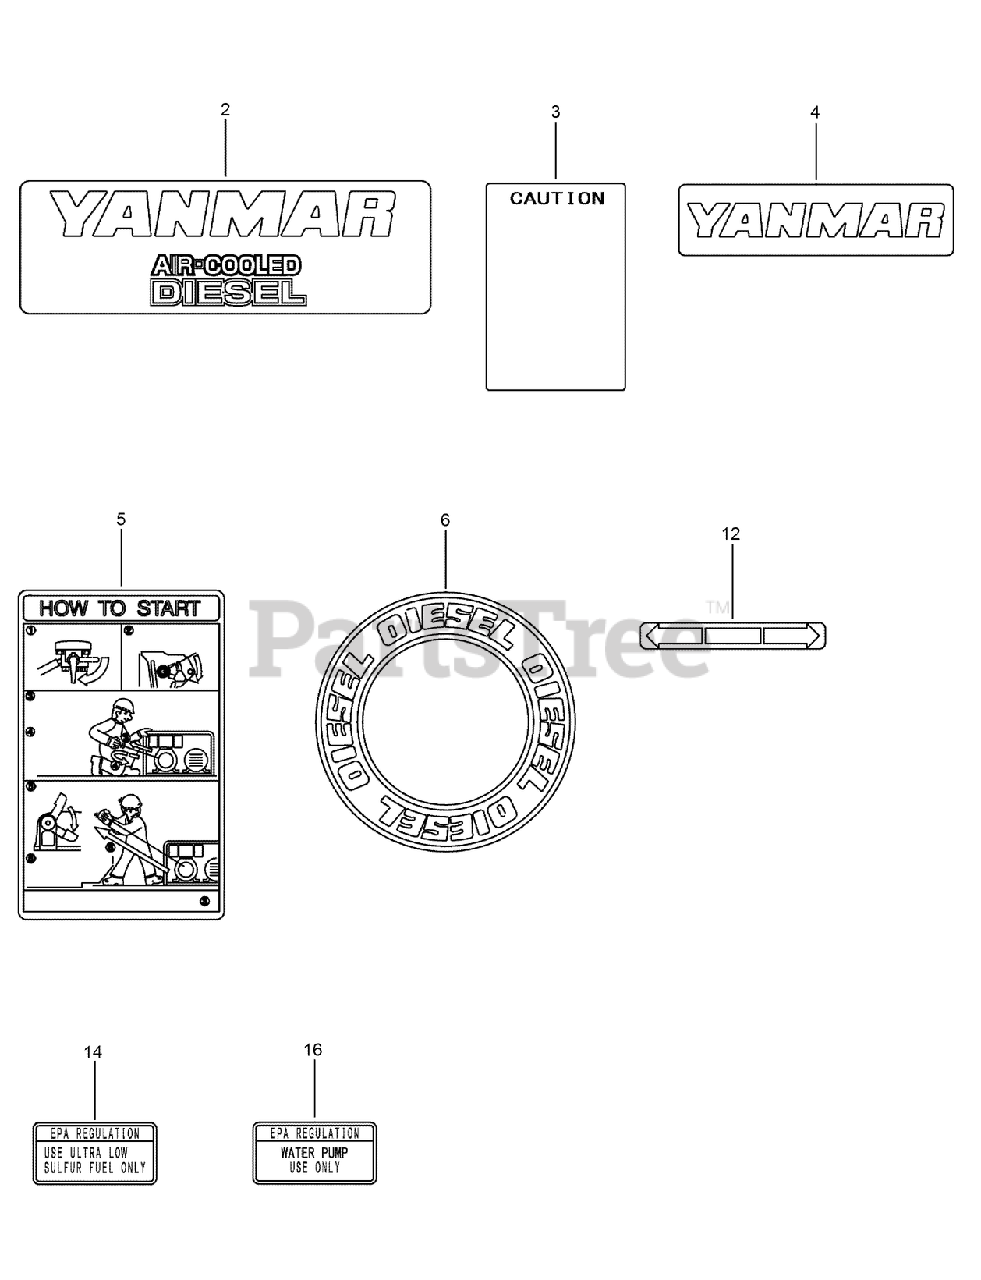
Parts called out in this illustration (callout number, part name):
2	LABEL-YANMAR
3	LABEL-CAUTION
4	LABEL-YANMAR
5	LABEL-HOW TO START
6	LABEL-DIESEL
12	LABEL-OPERATION
14	LABEL-CAUTION, FUEL OIL
16	LABEL-WATER PUMP
